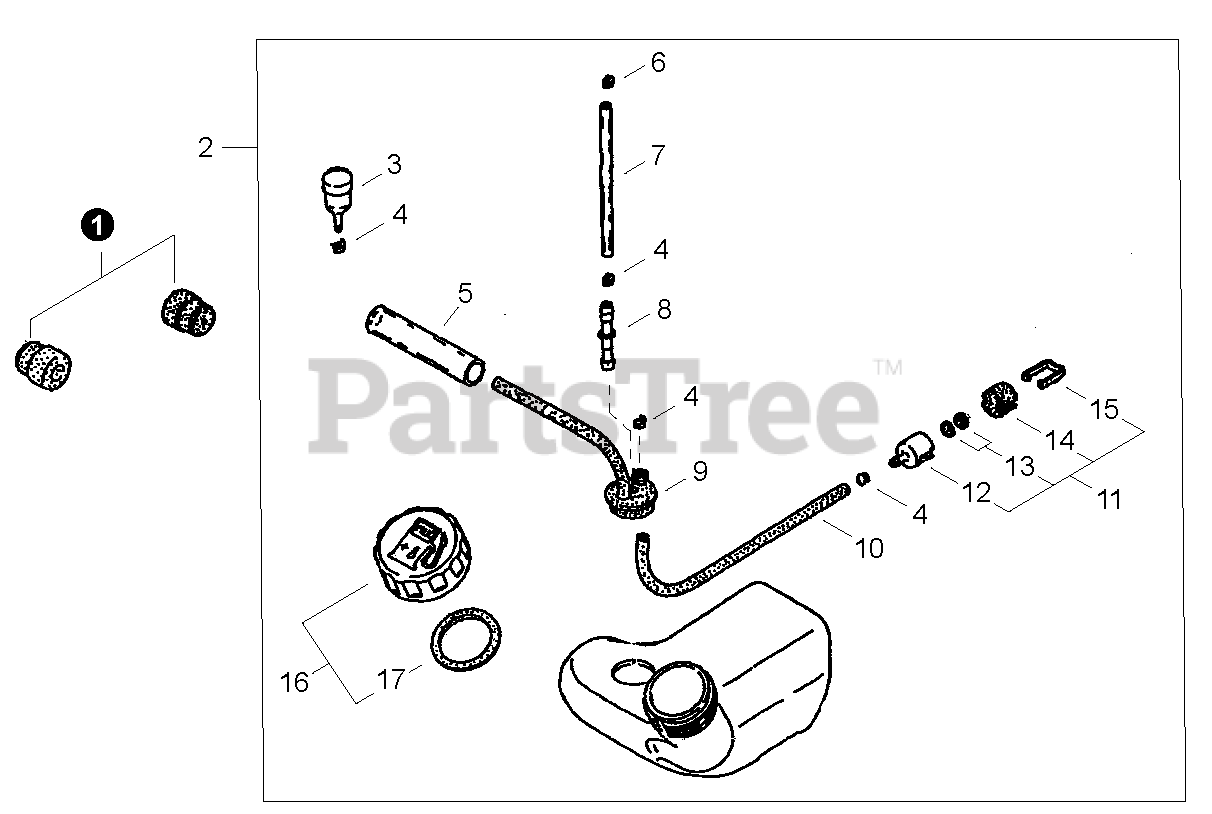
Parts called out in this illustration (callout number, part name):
1	CUSHION
2	TANK ASSY, FUEL
3	VENT ASSY
4	CLIP Ø6
5	PIPE
6	CLIP, SPRING Ø5.2
7	PIPE, FUEL RETURN
8	CONNECTOR, PIPE
9	GROMMET, FUEL W/VENT PIPE
10	PIPE, FUEL
11	FILTER ASSY, FUEL
12	WEIGHT, FUEL FILTER
13	SCREEN, FUEL INLET
14	FILTER, FUEL
15	CLIP, FILTER
16	CAP ASSY, FUEL
17	GASKET, FUEL CAP
